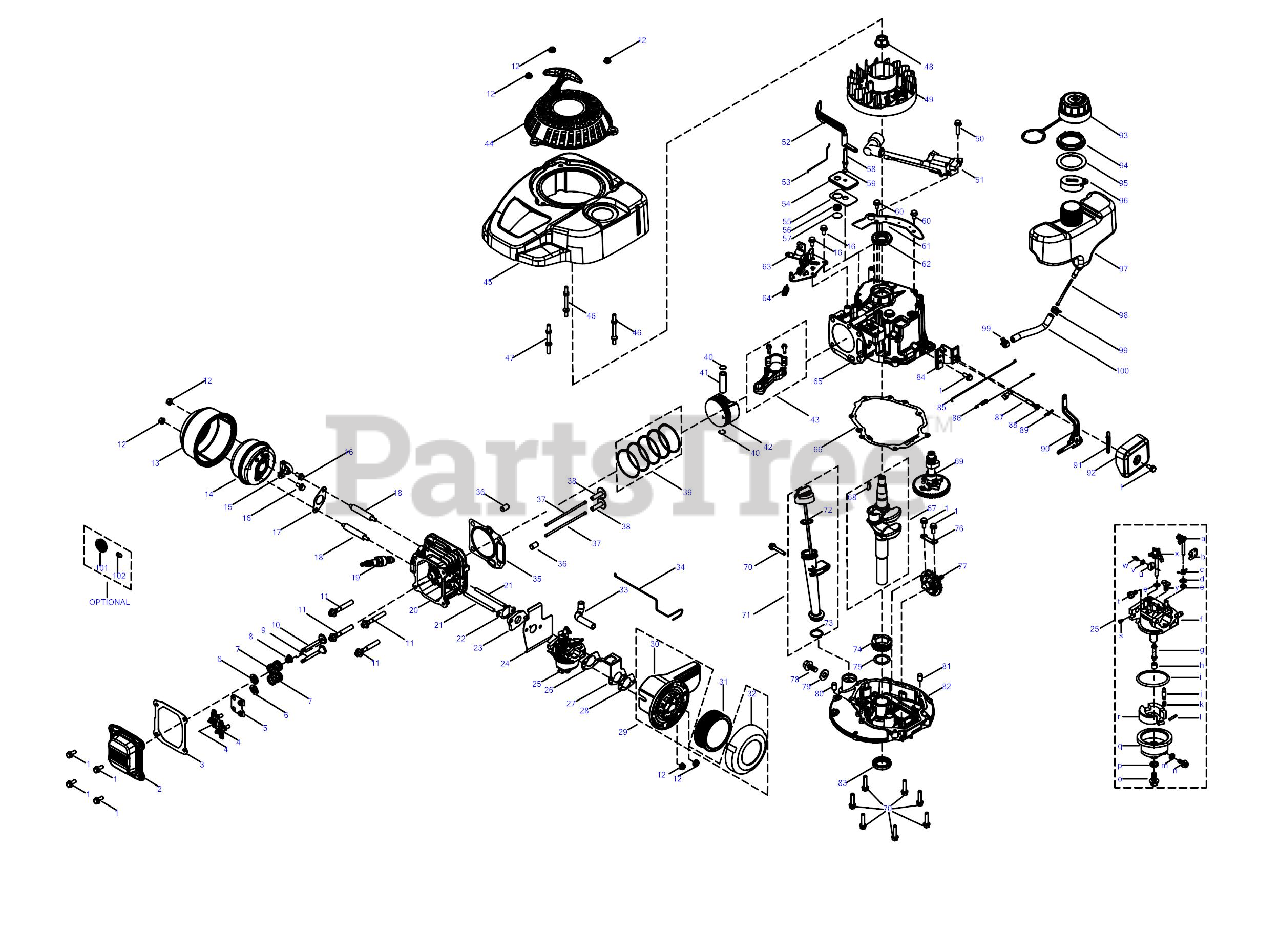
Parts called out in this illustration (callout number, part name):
1	Bolt M6?14
2	Valve Cover
3	Valve Cover Gasket
4	Rocker Arm Assembly
5	Push Rod Guide
6	Valve Spring Retainer
7	Valve Spring
8	Intake Valve Seal
9	Exhaust Valve
10	Intake Valve
11	Bolt M8?54 Cylinder Head
13	Muffler Shield
14	Muffler Assembly
15	Autochoke Temp-Comp Control
16	Bolt M6?12
17	Muffler Gasket
18	Muffler Stud M6?76
19	Spark Plug/F5RTC
20	Cylinder Head
21	Carb Stud M6?87
22	Carburetor Insulator Gasket
23	Carburetor Insulator
24	Carburetor Gasket
25	Carburetor Assembly
26	Air Filter Base Gasket
27	Choke Thermal Control Bracket
28	Air Filter Bracket Gasket
29	Air Filter Assembly
30	Air Filter Base
31	Air Filter Element, Paper
32	Air Filter Cover
33	Breather Hose
34	Temp Control Linkage
35	Cylinder Head Gasket
36	Cylinder Head Dowel Pin ?10?16
37	Push Rod
39	Piston Ring Set
40	Piston Pin Snap Ring
41	Piston Pin
42	Piston
43	Connecting Rod Assembly
44	Starter Recoil Assembly
45	Engine Shroud Assembly
46	Shroud Stud M6?75
47	Shroud Stud M6?73
48	Flywheel Nut M14
49	Flywheel
50	Bolt M6?25
51	Ignition Coil Assembly
53	Choke Linkage
54	Breather Cover Plate
55	Breather Gasket
56	Breather Valve Spring
57	Breather Valve
58	Air Vane Pivot Stud
59	Air Vane Pivot Washer
60	Bolt M6?10
61	Shroud Cover Plate
62	Upper Crankshaft Seal
63	Brake Assembly
64	Brake Spring
66	Crankcase Cover Gasket
67	Crankshaft Assembly
68	Flywheel Key
69	Camshaft Assembly
70	Bolt M6?28
71	Dipstick Assembly
72	Dipstick / Oil Fill Tube O-Ring
73	Dipstick / Oil Fill Tube O-Ring
74	Timing Gear
75	Crankshaft Thrust Washer
76	Governor Gear Mounting Plate
77	Governor Gear/Shaft Assembly
78	Oil Drain Plug
79	Oil Drain Plug Washer
80	Crankcase Cover Dowel Pin ?9?14
81	Crankcase Cover Dowel Pin ?7?14
82	Crankcase Cover
83	Lower Crankshaft Seal
84	Component Bracket
85	Throttle Linkage
86	Throttle Linkage Spring
87	Governor Arm Shaft
88	Governor Seal
89	Governor Arm Shaft Cotter Pin
90	Governor Arm Assembly
91	Governor Spring
92	Governor Shield
93	Fuel Cap Assembly
94	Fuel Tank Nut
95	Fuel Tank Upper Grommet
96	Fuel Tank Dust Cap
97	Fuel Tank
98	Fuel Filter
99	Fuel Hose Clamp
100	Fuel Hose
101	Spark Arrestor
102	Spark Arrestor Screw
